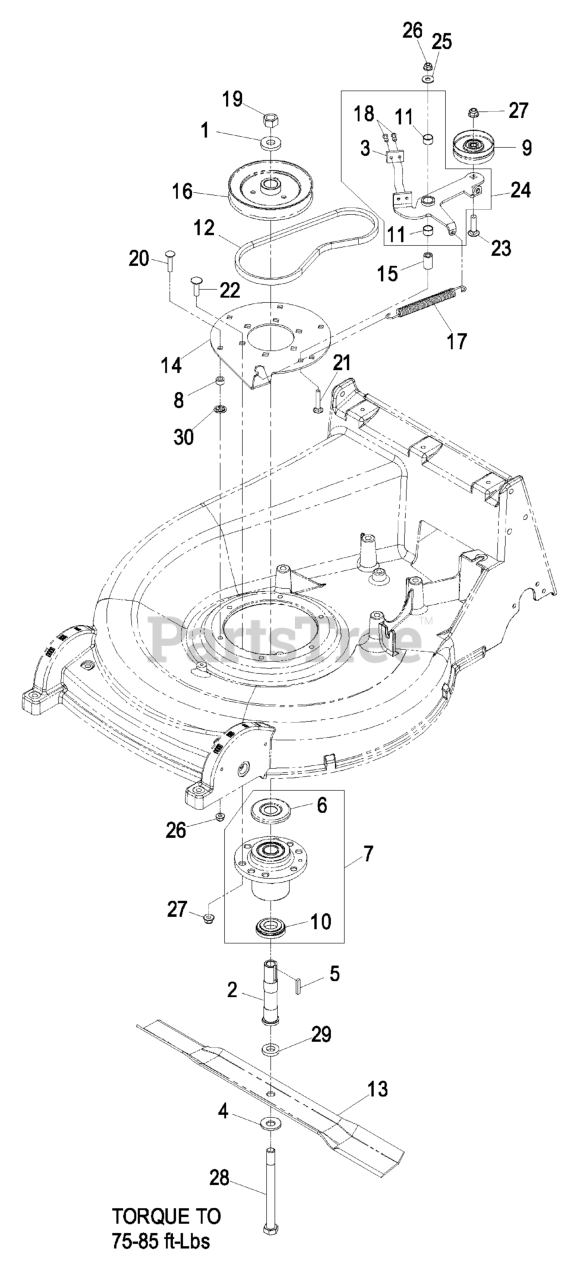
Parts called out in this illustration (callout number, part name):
1	WASHER-RETAINER, SHEAVE
2	TUBE-SPINDLE, SHORT
3	PAD-BRAKE
4	WASHER-SPRING
6	GUARD-BEARING, TOP
7	KIT, CUTTER HOUSING
8	SPACER
10	SPACER-GUARD, BOTTOM
11	BEARING
14	PLATE,CUTTER HOUSING
15	BUSHING-ARM, IDLER
16	SHEAVE-SPINDLE
17	SPRING-BRAKE
18	RIVET-POP
19	NUT-HEX
20	BOLT-CARR
21	BOLT-CAR
22	Bolt-Carriage 3/8-16 X 1 1/4
23	SCREW-CARR
25	WASHER-FLAT
26	NUT-HF, NI
27	NUT-HF, NI
28	SCREW-HH YZ
30	RING-RETAINING
31	ASM,CUTTER HOUSING COMPLE
